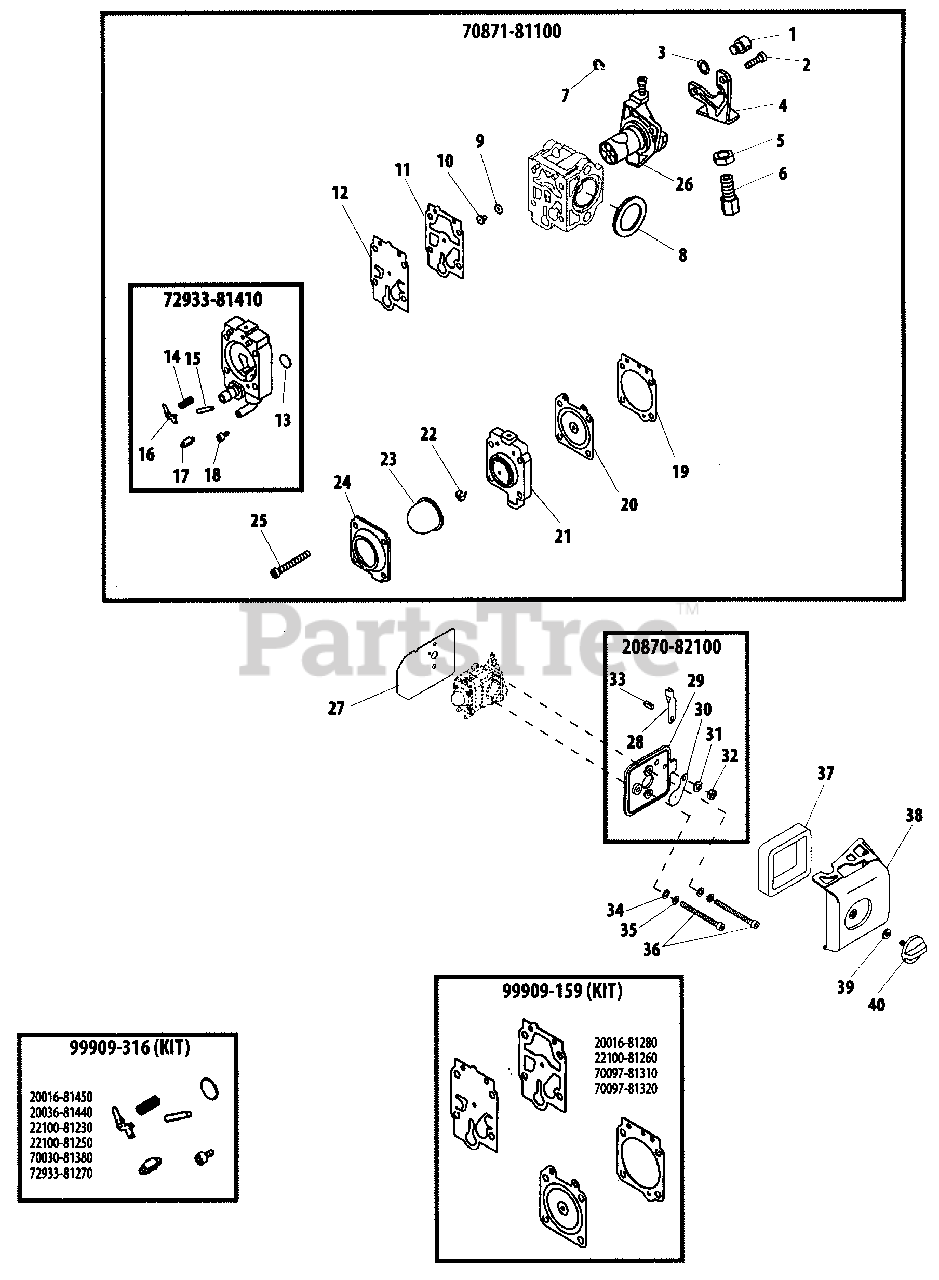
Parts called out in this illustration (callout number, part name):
1	SWIVEL
2	SCREW
3	WASHER
4	BRACKET, THROTTLE CABLE
5	NUT, ADJUSTER LOCK M7
6	ADJUSTER, THROTTLE CABLE
7	E-RING
8	RING, PACKING
9	O-RING
10	JET
11	GASKET, PUMP
12	DIAPHRAGM, PUMP
13	SCREEN, FUEL INLET
14	SPRING, METERING LEVER
15	PIN, METERING LEVER
16	LEVER, METERING
17	VALVE, INLET NEEDLE
18	SCREW
19	GASKET, METERING DIAPHRAGM
20	DIAPHRAGM, METERING
21	BODY ASSY, PURGE
22	VALVE, CHECK
23	BULB, PURGE
24	RETAINER, PURGE BULB
25	SCREW
26	THROTTLE VALVE ASSY
27	GASKET
28	LEVER, CHOKE
29	CASE, AIR FILTER
30	PLATE, CHOKE
31	WASHER, SPRING 6
32	U-NUT M6
33	SHAFT, CHOKE
34	WASHER, FLAT 5.5×10×0.8
35	WASHER, SPRING 5
36	BOLT 5×60
37	FILTER, AIR
38	COVER, AIR FILTER
39	WASHER 5
40	THUMBSCREW
20870-82100	AIR FILTER CASE ASSY
70871-81100	CARBURETOR
72933-81410	BODY ASSY, PUMP
99909-159	GASKET / DIAPHRAGM KIT
99909-316	VALVE KIT, INLET NEEDLE
